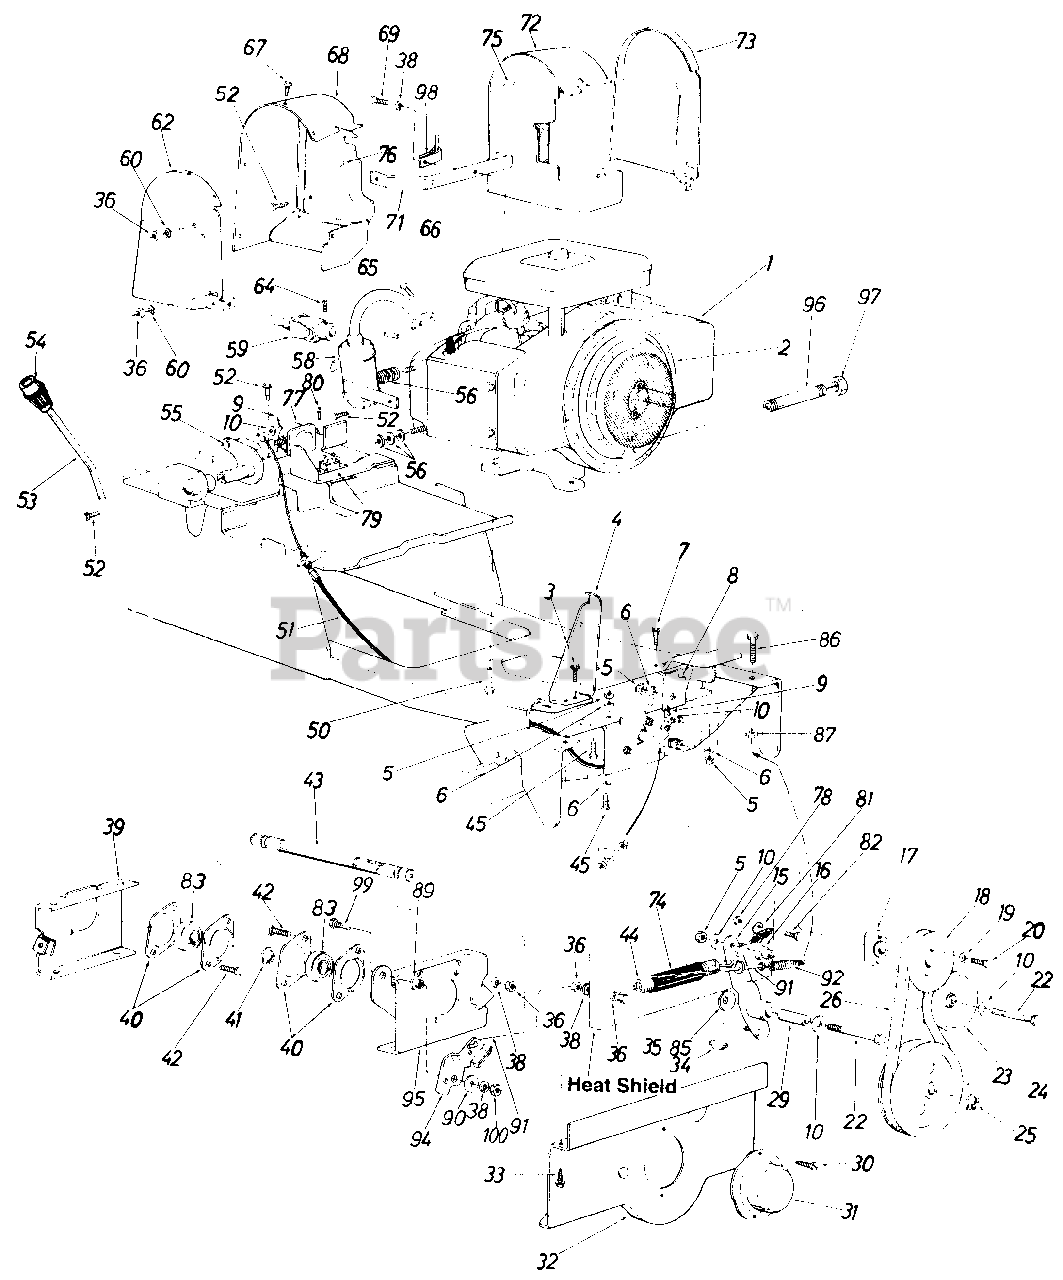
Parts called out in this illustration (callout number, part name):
1	Engine
2	Mylar Foam Strip
3	Hex Wash. Hd. Self-Tap Scr. 1/4-20 x .75" Lg.
6	L-Wash. 3/8" I.D.
7	Hex Wash. Hd. Self-Tap Scr. 5/16-18 x .75" Lg.
10	Fl-Wash. .38" I.D. x 1.25" O.D. x .100" Thk.
17	Pulley Spacer
18	1/2" V-Pulley 4.75" O.D. (Engine)
19	L-Wash. 3/8" I.D. H.D.
20	Hex Scr. 3/8-16 x 2.00" Lg.
22	Hex Bolt 3/8-16 x 2.50" Lg.
23	Flat Idler Pulley
24	1/2" V-Pulley 7.00" O.D. (PTO)
25	Snap Ring
26	"V"-Belt 1/2" x 41" Lg. (PTO)
29	Spacer .375" I.D. x .62" O.D. x 1.830" Lg.
30	Hex "B" Tap Scr. #10 x .50" Lg.
34	#91 Hi-Pro Key
35	Hex Bolt 5/16-18 x 1.25" Lg.
36	Hex Nut 5/16-18 Thd.
38	L-Wash. 5/16" I.D.
40	1.00" Dia. Brg. w/Flangette
41	Snap Ring
42	Carr. Bolt 5/16-18 x .75" Lg.
43	Spline Shaft
44	Extension Spring (PTO Clutch)
45	Hex Scr. 3/8-16 x 1.00" Lg.
50	Hex Wash. Hd. Self-Tap Scr. 3/8-16 x 1.25" Lg.
51	PTO Control Cable
52	Hex Wash. Hd. Self-Tap Scr. 1/4-20 x .50"
53	PTO Handle
54	Shift Knob
55	PTO Actuator Lever Ass'y.
56	Fl-Wash. .312" I.D. x 1.620" O.D. x .060
58	Muffler Ass'y. Comp.- R.H.
59	Universal Joint Ass'y. Comp.
60	Fl-Wash. .312" I.D. x .630" O.D.
62	Shroud Outer - R.H.
64	Sq. Hd. Set Scr. 5/16-18 x .38" Lg. (Cup Point)
65	Sq. Key 1/4" x 2.00" Lg.
66	Hex Wash. Hd. Scr. 1/4-20 x 5/8" Lg.- Grade 5
67	Hex "AB" Tap Scr. #10 x .50" Lg.
68	Shroud Cover - R.H.
69	Hex Bolt 5/16-24 x .75" Lg.
71	Shroud Support Brkt.
72	Shroud Cover - L.H.
73	Shroud Outer - L.H.
74	Spring Cover Tubing (PTO Clutch)
75	Shroud Inner Ass'y.- L.H.
76	Shroud Inner Ass'y.- R.H.
77	Solenoid
78	Hex Bolt 1/4-20 x 1/2" Lg.
79	Circuit Breaker
80	Truss Mach. Scr. #10 x .50" Lg.
81	Safety Switch (PTO)
82	L-Wash. 1/4" I.D.
83	Ball Bearing
85	Bell-Wash. .39" I.D. x 1.13"
86	Hex Bolt 3/8-16 x 1.5" Lg.
87	Hex Cent. L-Nut 3/8-16 Thd.
89	Shoulder Spacer
90	Fl-Wash. .33" I.D. x 1.25" O.D.
91	PTO Brake Rod
92	Extension Spring 2.15" Lg.
95	PTO Brg. Retainer Brkt. Ass'y.
96	Pipe Nipple 3/8" x 5" Lg.
97	Oil Drain Cap
98	Clamp
99	Hex Bolt 5/16-24 x .75" Lg.
100	Hex Nut 5/16-24 Thd.
